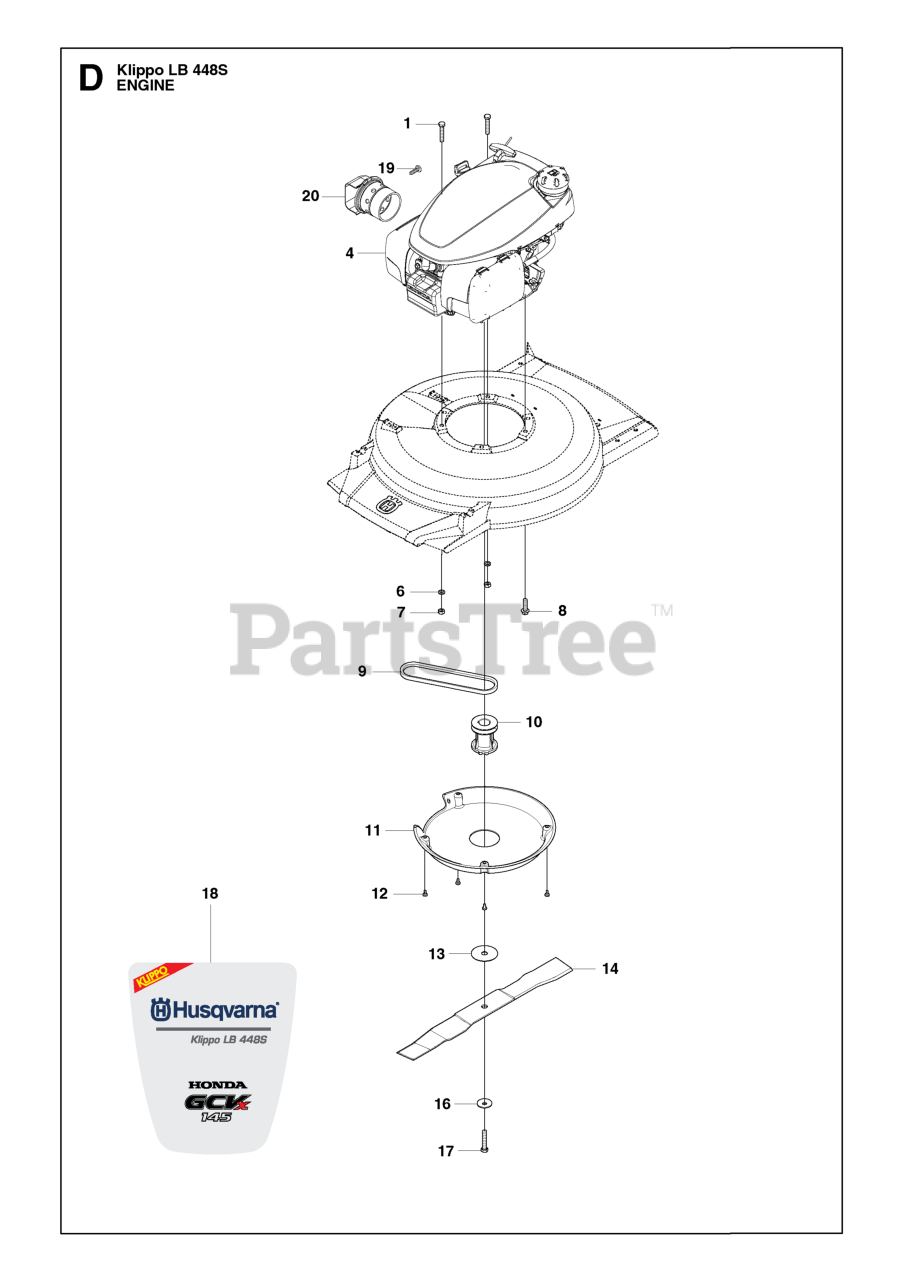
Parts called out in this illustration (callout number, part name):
6	WASHER BRB 8.4X17
7	LOCKNUT M8
12	SCREW ITXPANTT M5X10 ZPB (A00
